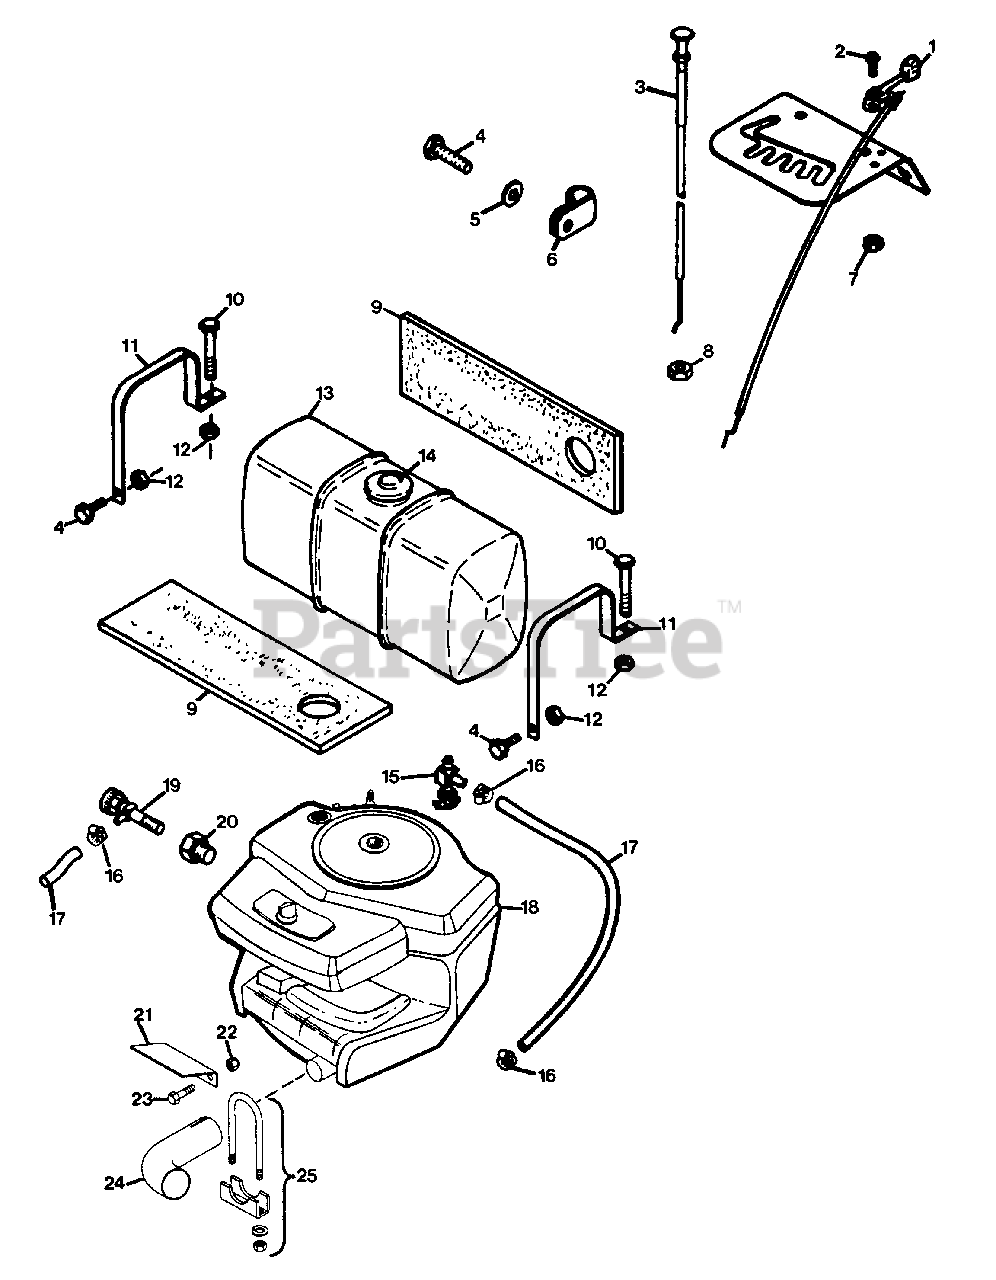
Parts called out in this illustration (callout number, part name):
1	LEVER, CONTROL
2	SCREW, MACH. 10-24X.50 PHD
3	CONTROL, CHOKE
4	BOLT, HEX 1/4-20X.625
5	WASHER, FLAT .281X.625X.065
6	CLAMP
7	NUT, LOCK 10-24
8	NUT, JAM 3/8-24 HEX
9	FITTING, TANK
10	BOLT, HEX 1/4-20X1.75
11	STRAP, FUEL TANK
12	NUT, LOCK 1/4-20
13	TANK, FUEL
14	CAP, GAS TANK
15	BUSHING
16	CLAMP, HOSE
17	LINE, FUEL
18	ENGINE, 16 HP B&S
19	COCK, OIL DRAIN
20	ADAPTOR, OIL DRAIN
21	DEFLECTOR, EXHAUST
22	NUT, LOCK 5/16-18
23	BOLT, HEX 5/16-18X.75
